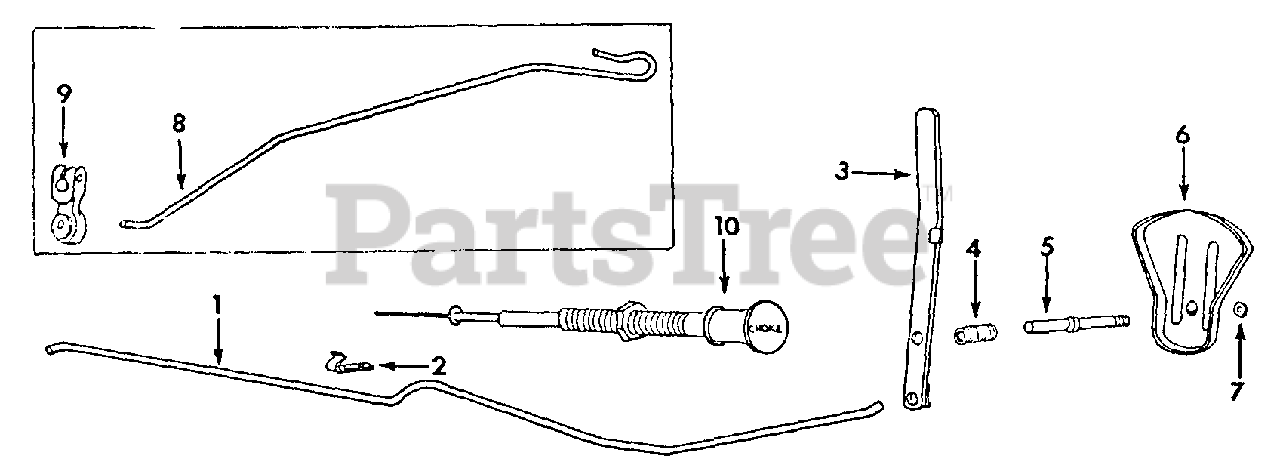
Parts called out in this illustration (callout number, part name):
1	ROD, GOVERNOR CONTROL
2	CLIP, GOVERNOR CONTROL ROD
3	LEVER, GOVERNOR CONTROL
4	SPRING, GOVERNOR CONTROL LEVER
5	PIN, GOVERNOR CONTROL PIVOT
6	SECTOR, GOVERNOR CONTROL
7	WASHER, GOVERNOR CONTROL PIVOT PIN
8	ROD, CHOKE
9	LEVER, CARBURETOR CHOKE
10	CABLE CHOKE CONTROL
